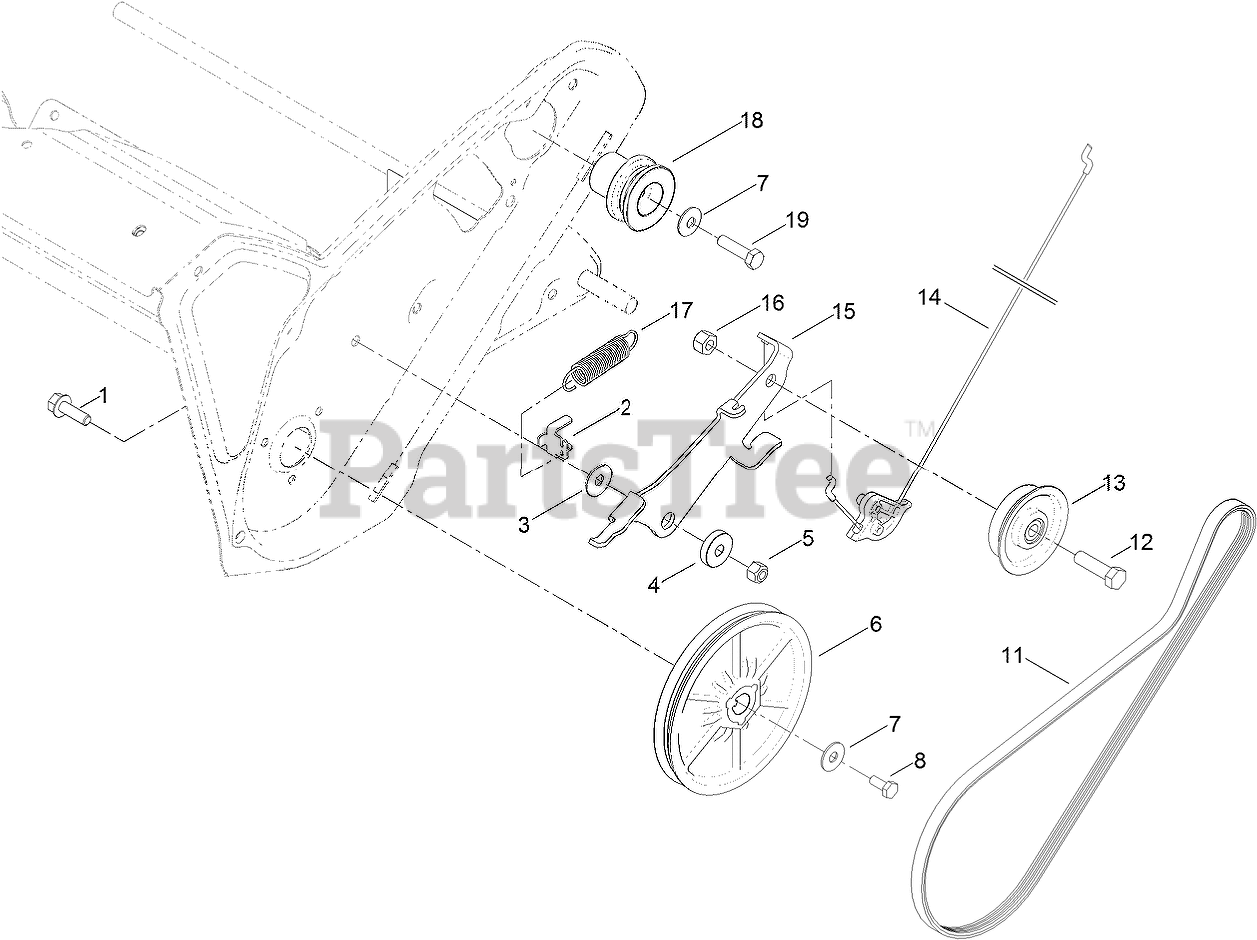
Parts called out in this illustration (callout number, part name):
1	SCREW-HHF
2	CLIP-SPRING, BRAKE
3	WASHER
4	BUSHING-PIVOT
5	NUT-LOCK, NI
6	PULLEY
7	WASHER-BELLEVILLE
8	SCREW-HH
11	BELT-DRIVE
12	SCREW-HH
13	PULLEY-IDLER
14	CABLE-CLUTCH
15	ARM-IDLER
16	NUT-LOCK, CONE
17	SPRING-EXTENSION
18	PULLEY-ENGINE
19	SCREW-HH
